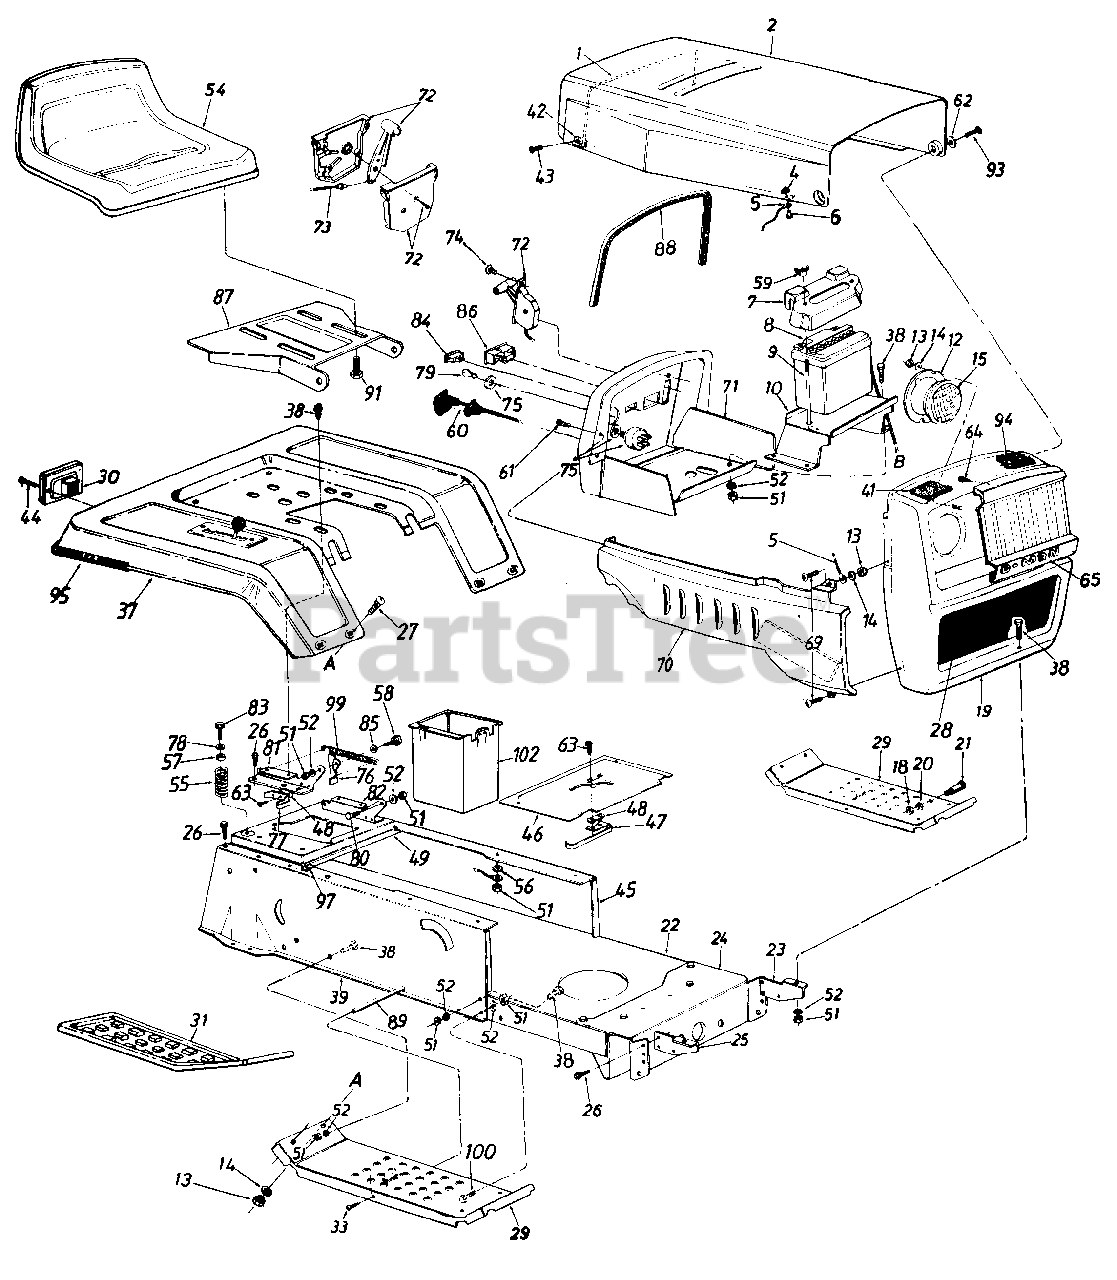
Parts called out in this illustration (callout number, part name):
1	Hood Spring
5	Hood Stop 7" Lg.
6	Pop Rivet .188" Dia.
7	Battery Cover
8	12 Volt Battery
9	Battery Hold Down Rod
10	Battery Bracket
12	Headlight Retainer
13	Hex Nut 1/4-20 Thd.
14	l L-Wash 1/4" I.D.
15	Headlight
18	Hex Nut 3/8-16 Thd.
21	Shld. Bolt .50" Dia. x .84
22	Lower Frame
23	Grille Mount Brkt.
24	Front Pivot Brkt.
27	Carriage Bolt 1/4-20 x .50" Lg.
28	Grille Insert
29	Running Board
30	Taillight
31	Foot Pad L.H.
33	Truss Mach. Scr. 5/16-18 x .75" Lg.
37	Fender
38	Hex Bolt 5/16-18 x .75" Lg.
42	Hood Spring Retainer
43	Self-Tap Scr. .5" Lg.
44	Truss AB-Tap Scr. #6 x .62"
47	Reverse Safety Switch
48	Insulator Nut Plate
49	Hitch Plate
51	Hex Nut 5/16-18 Thd.
52	L-Wash. 5/16" I.D.
54	Seat Ass'y.
55	Compression Spring
56	Ext. L-Wash. 5/16" I.D.
57	Bushing
58	Shld. Bolt .437" Dia. x .268"
59	Wing Nut 1/4-20 Thd. Plastic
60	Choke Control 48" Lg.
61	Truss Mach. Tap Scr. #10 x .50" Lg.
62	Washer .39" I.D. x .62" O.D.
63	Hex Wash. Hd. AB-Tap Scr. #8 x .50
64	Self-Tap Scr. #8 x .5" Lg.
65	Bezel
69	Truss Hd. Scr. 1/4-20 x .75" Lg.
70	R.H. Grille Side Panel w/Foam
71	Dash Panel Ass'y.
72	Throttle Control Box Ass'y.
73	Throttle Control Wire 35"
74	Truss Mach. AB-Tap Scr. #10 x .5" Lg.
75	Ignition Switch
76	Seat Lift Bracket
77	Spring Switch
78	Fl-Wash. .344" I.D.
79	Ignition Key
80	Shld. Bolt .437" Dia. x .162"
81	Seat Pivot Brkt. Support R.H.
82	Seat Pivot Brkt. Support L.H.
83	Hex Hd. Tap Scr. 5/16-18 x 1" Lg.
84	Light Switch
85	Spr-Wash. .445" I.D. x .75" O.D.
86	Ammeter
87	Seat Pivot Bracket
88	Molding Strip 27" Lg.
89	Running Board Rod
91	Hex Wash. Hd. Tap Scr. 3/8-16 x .75" Lg.
93	Shld. Bolt .375 Dia. x .125
94	L-Nut 1/4-28 Thd.
95	Trim Strip 31.0" Lg.
97	Speed Nut #10Z
99	Extension Spring 5.31" Lg.
100	Truss Hd. Scr. 5/16-18 x 1.0" Lg.
102	Utility Box
